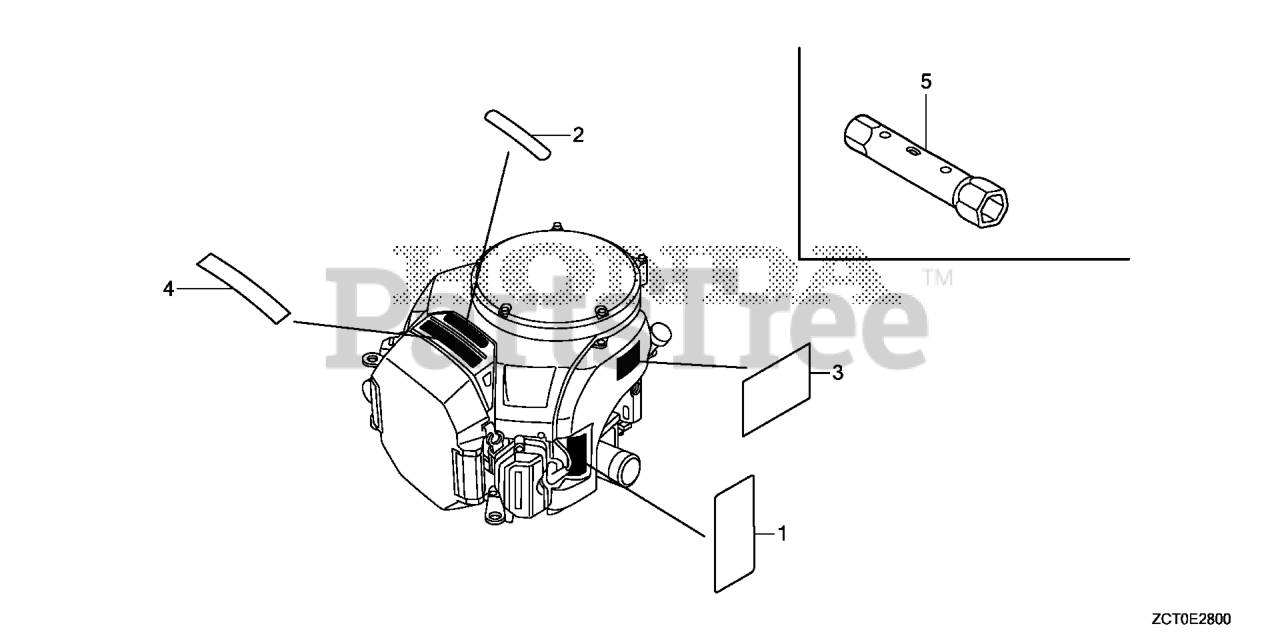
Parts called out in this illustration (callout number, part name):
1	MARK, OPERATOR CAUTION (ENGLISH)(MADE IN CHINA)
2	EMBLEM (GXV690)
4	MARK, HONDA
